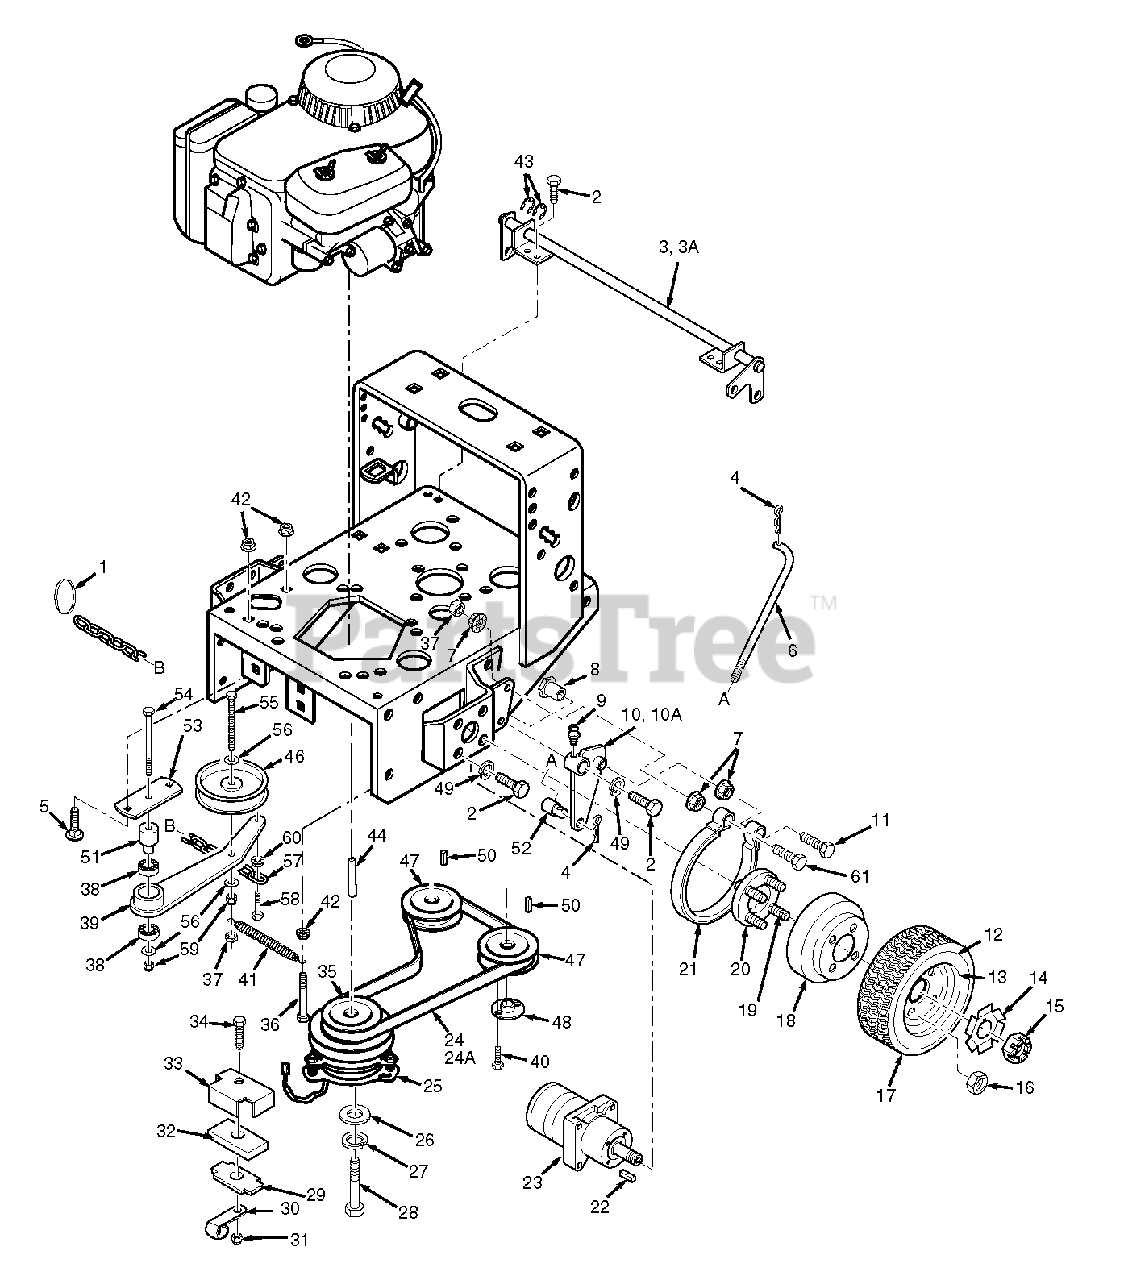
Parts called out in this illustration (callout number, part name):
1	Ring, Split
2	Bolt, 3/8-16 x 1' Hex Head
3	Brake Shaft Assembly Weldment, 16' Small Frame
3A	Brake Shaft Assembly Weldment, 20' Large Frame
4	Hair Pin Cotter, .094 x 1.62
5	Carrage Bolt, 5/16-18 x .75'
6	Rod, Brake Lower
7	Nut, 3/8-16 Serr. Flange
8	Bushing, Brake
9	Grease Fitting
10	Brake Actuator Weldment-LH
10A	Brake Actuator Weldment-RH
11	Bolt, 3/8-16 x 2-1/4'
12	Tire, 16 x 6.50, 4 ply
13	Rim Assy
14	Lock Washer, Wheel Motor
15	Hex Castle Nut, 3/4-28 UNEF
16	Nut, Lug
17	Wheel Assy.,
18	Brake Drum
19	1/2-20 Serrated Bolt
20	Hub, Wheel
21	Brake Band, 7.5'
22	Key, 3/16 X .75 Woodruff
23	Wheel Motor
24	Belt, Pump Drive, 16' Small Frame
24A	Belt, Pump Drive, 20' Large Frame
25	Electric Clutch
26	Flat Washer .469 x 1.75 x .25
27	Lock Washer, 7/16'
28	Hex Head Bolt, 7/16-20 x 2-3/4'
29	Plate, Backing
31	Nut, 5/16-18 Elastic Stop
32	Rubber Pad, Clutch Stop
33	Retainer, Clutch Stop
34	Hex Head Bolt, 5/16-18 x 1.75'
35	Pulley, Pump Drive Engine
36	Hex Head Bolt, 5/16-18 x 2.75'
37	Nut, 3/8-16 Center Lock
38	Ball Bearings
39	Idler Arm Weldment, Pump
40	Bolt, Hex Head 1/4-20 x 1' Grd 8
41	Spring, Pump Belt Idler
42	Nut, 5/16-18 Serr. Flange
43	Retaining Ring, 3/4' Ext. 'E'
44	Key, 1/4x1/4 x 3.75'
45	Flat Washer, 3/8'
46	Pulley, Idler 4.5'
47	Pulley, Pump Shaft
48	Tapered Hub
49	Lockwasher, 3/8'
50	Key, 5.0 x 5.0 x 25mm
51	Pivot, Idler (Long)
52	Swivel Joint
53	Base, Idler Pivot
54	Bolt, Hex Head 3/8-16 x 3'
55	Bolt, Hex Head 3/8-16 x 2.75'
56	Flatwasher 3/8'
57	Chain
58	Bolt, Hex Head 1/4-20 x 1.25'
59	Nut, Hex Elastic Stop 3/8-16
60	Nut, Serrated Flange 1/4-20
61	Bolt, Hex Head 3/8-16 x 2.63'
